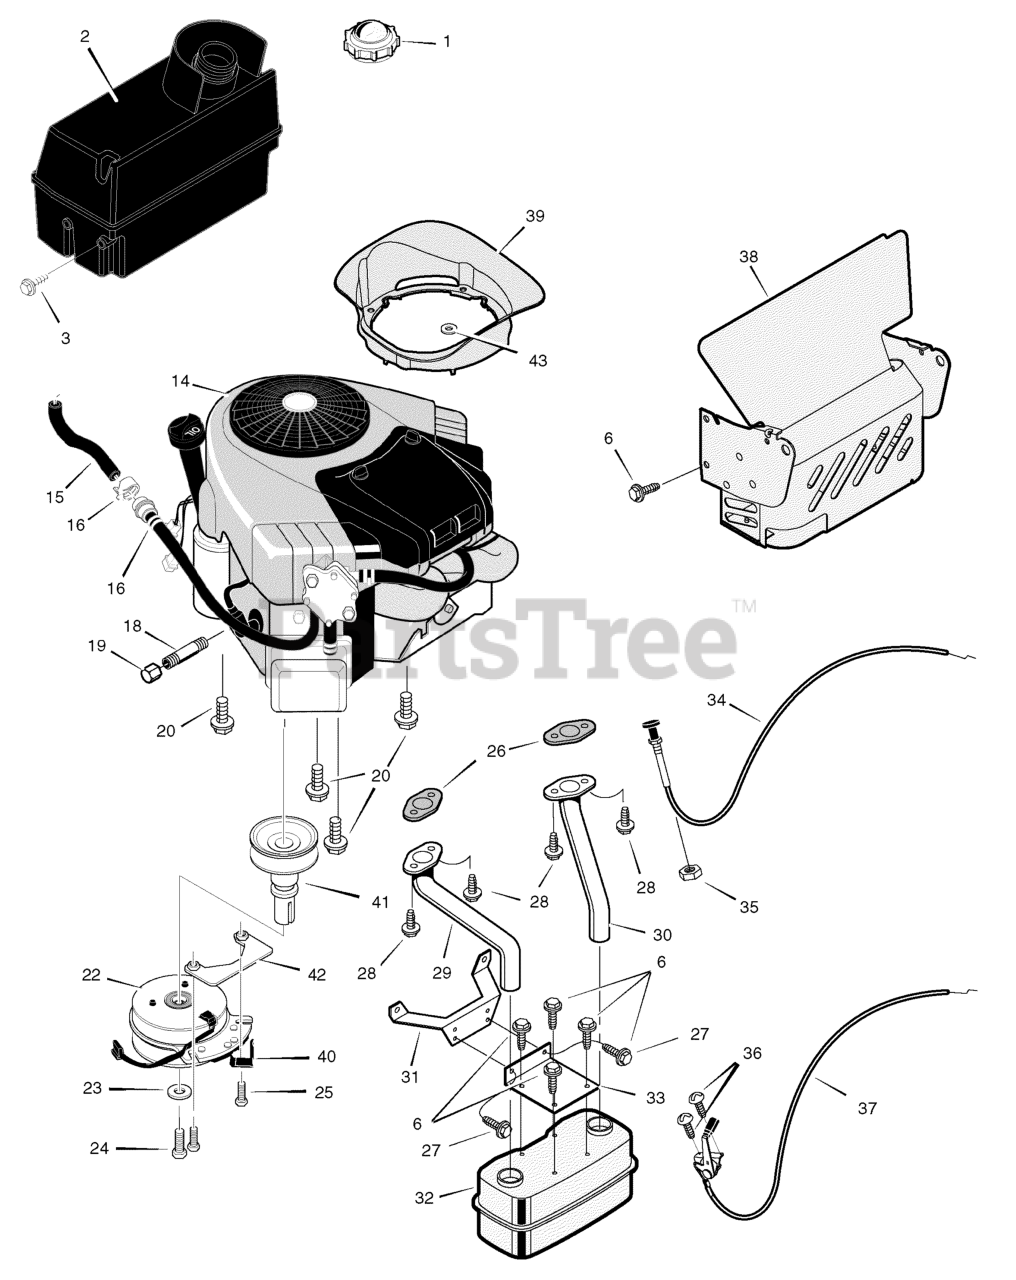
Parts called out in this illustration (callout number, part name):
1	Cap, Fuel
2	Tank, Fuel
6	Screw
14	Engine
15	Line, Fuel (Must cut to length)
16	Clamp, Hose
18	Pipe, Oil Drain
19	Cap, Oil Drain
20	Bolt
22	Clutch, Electric
23	Washer
25	Screw
26	Gasket, Exhaust
27	Screw
28	Bolt
29	Tube, Right Exhaust
30	Tube, Left Exhaust
31	Bracket, Muffler Mount
32	Muffler
33	Bracket, Muffler
35	Nut
36	Screw
37	Control, Throttle
38	Shield, Heat
40	Guide, Belt
41	Adapter, Pulley
42	Plate, Brake
43	Nut, Push
